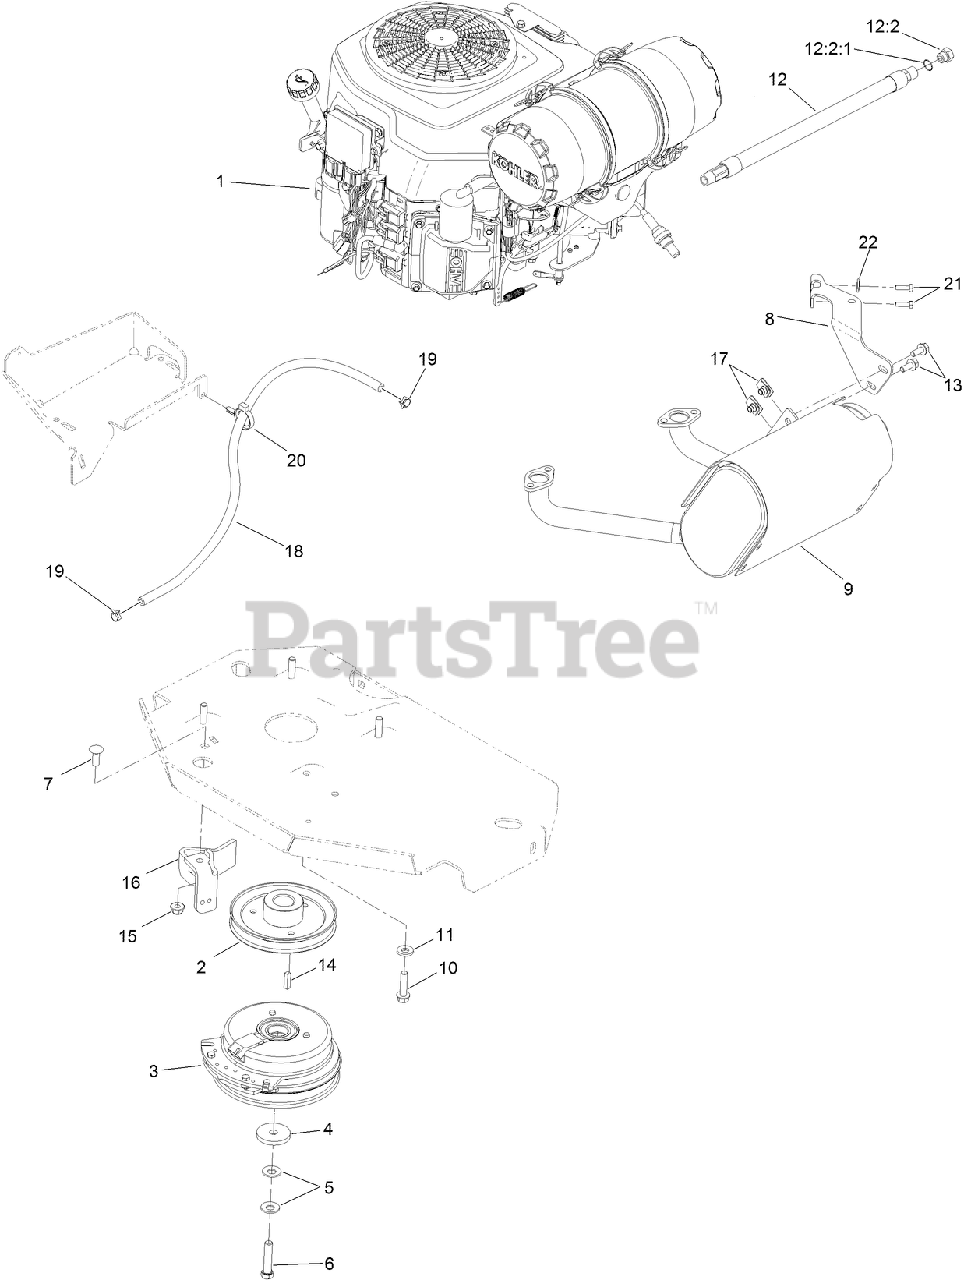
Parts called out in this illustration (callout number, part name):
1	ENGINE-KOHLER
2	SHEAVE
3	CLUTCH KIT
4	WASHER-CLUTCH
5	WASHER-SPRING
6	SCREW-HH W/LOCTITE
7	SCREW-CARR
8	MUFFLER BRACKET KIT
9	MUFFLER
10	SCREW-HWH
11	WASHER-BELLEVILLE
12	OIL DRAIN HOSE ASM
12:2	PLUG-HH
12:2:1	O-RING
13	SCREW-HHF
15	NUT-HF, NI
16	CLUTCH-ANCHOR
17	NUT-U
18	HOSE-FUEL
19	CLAMP-HOSE
20	CLAMP-HOSE
21	SCREW-HH
22	WASHER-SPRING
